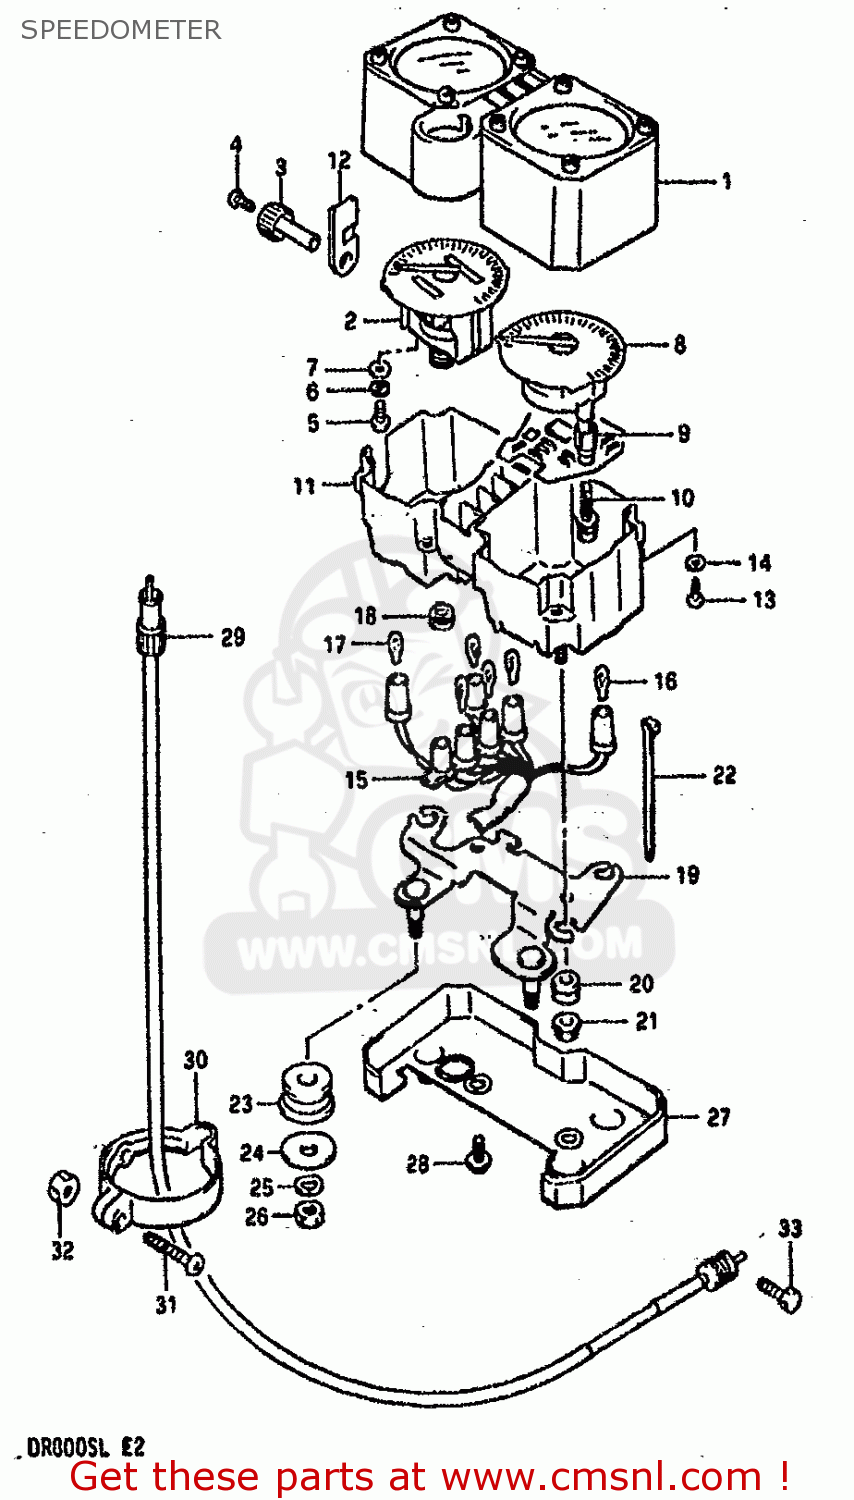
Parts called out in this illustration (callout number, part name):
1	HOOD,METER
2	SPEEDOMETER
3	KNOB,TRIP
4	SCREW,TRIP KNOB
5	SCREW
6	LOCK WASHER
7	WASHER 3.3X8X0
8	TACHOMETER
9	SPACER
10	SCREW
11	CASE,METER
12	CUSHION,METER
13	SCREW
14	LOCK WASHER
15	SOCKET,METER
16	BULB(12V3W,WB371,T7)
17	BULB(12V1.7W,WB372,T7)
18	CAP
19	BRACKET,METER
20	CUSHION,METER
21	NUT
22	CLAMP
23	CUSHION,METER BRACKET
24	WASHER (8.5X20X1.6)
25	WASHER,LOCK,8.
26	NUT ,8MM
27	COVER,SPEEDOMETER LWR
28	SCREW
29	CABLE ASSY
30	CLAMP,CABLE (BLUE)
31	SCREW
32	NUT
33	BOLT
